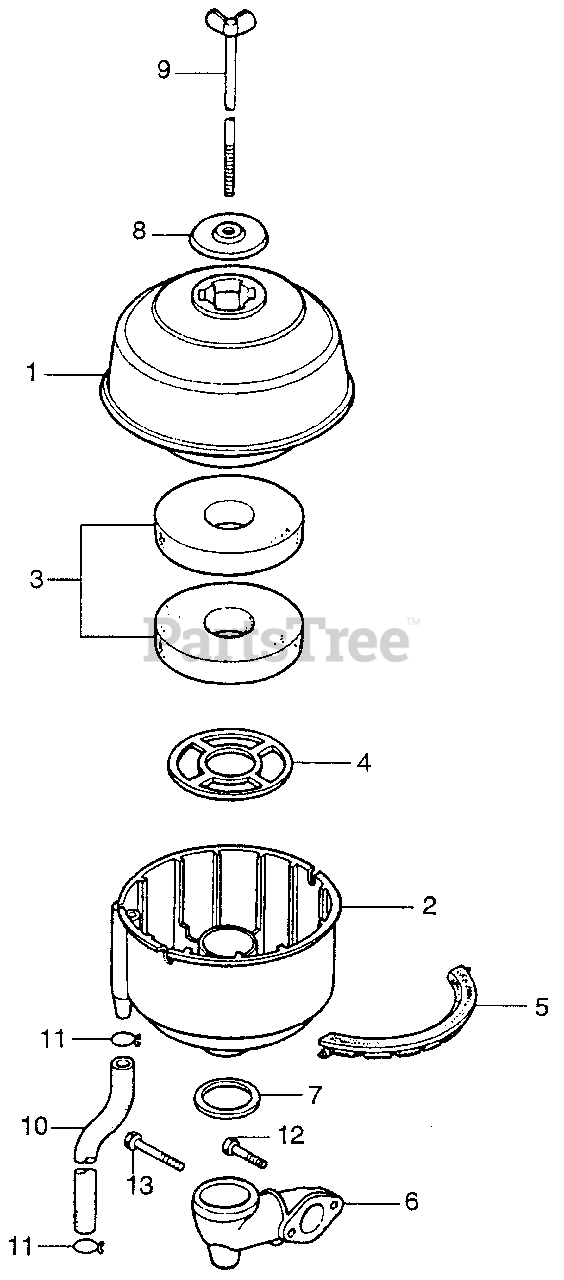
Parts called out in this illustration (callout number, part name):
1	BODY, CLEANER
2	PAN, AIR CLEANER OIL
3	ELEMENT, AIR CLEANER
4	GRID, AIR CLEANER
5	GASKET, OIL CLEANER
6	ELBOW, AIR CLEANER
7	GASKET, IN. ELBOW
8	CAP, AIR CLEANER
9	BOLT, AIR CLEANER
10	BULK HOSE, FUEL (8X1000) (8X250)
11	CLIP, TUBE (B12.5)
12	BOLT, FLANGE (6X25)
13	BOLT, FLANGE (6X45)
